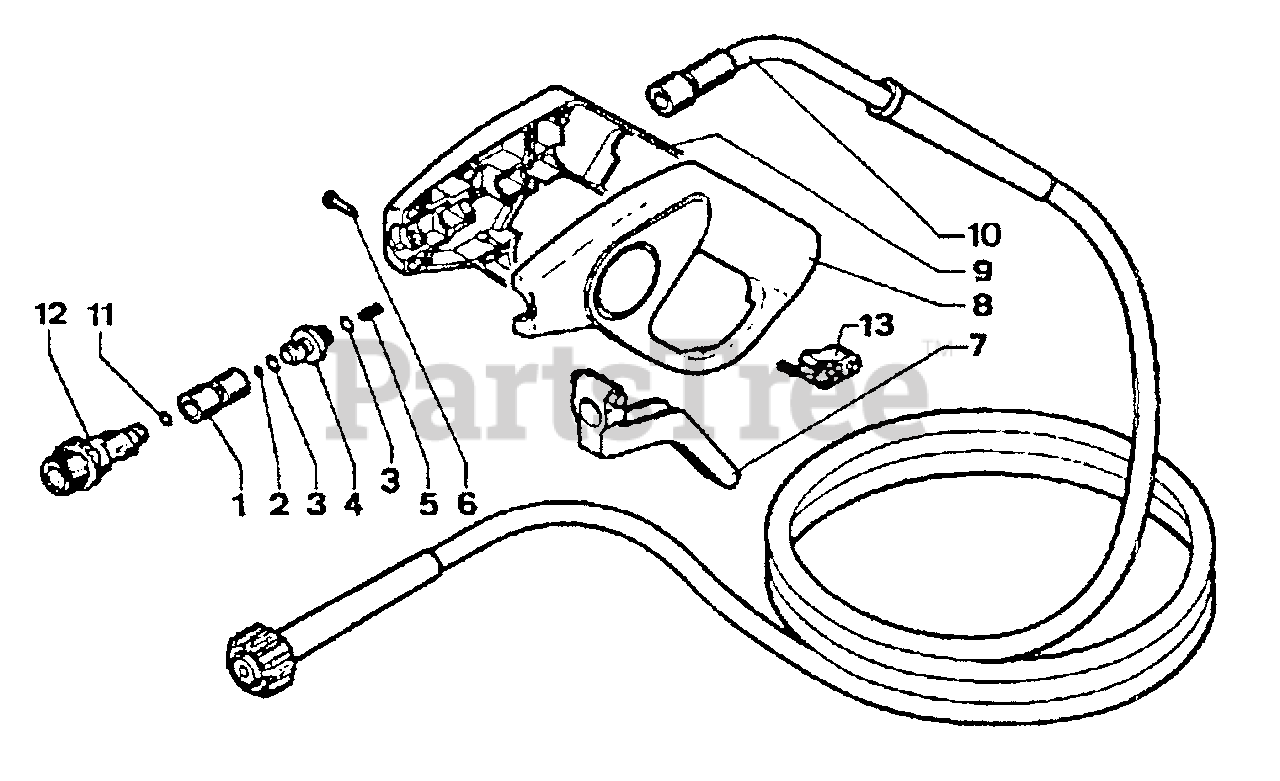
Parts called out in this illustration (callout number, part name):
1	BODY, PISTOL UNLOADER
2	O-RING 0.118×.079
3	O-RING 0.302×.070
4	SHUTTER
6	SCREW M3×16
7	TRIGGER, THROTTLE
8	HOUSING, LEFT, PLASTIC - BLACK
9	HOUSING, RIGHT, PLASTIC - BLACK
10	HOSE, HIGH PRESSURE, 7 MM
11	O-RING 0.299×.103
12	ADAPTOR
13	LATCH - RED
